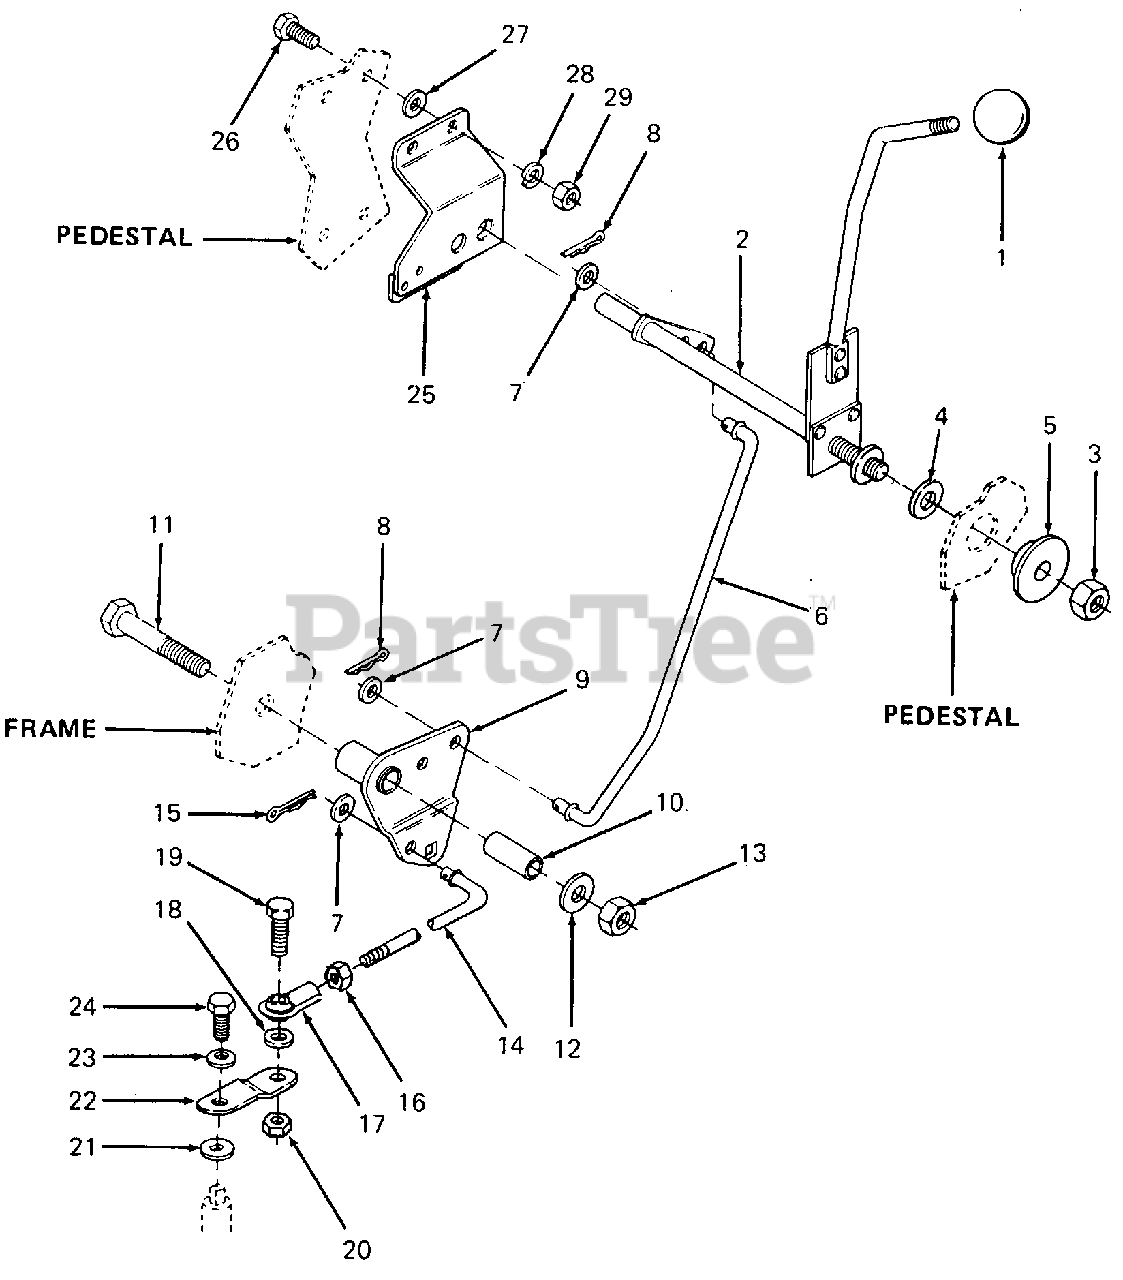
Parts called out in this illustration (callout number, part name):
1	Knob, Control
2	Shifter Assy
3	Nut, Hex Top Lock, 1/2-20
4	Washer, Friction
5	Spacer, Shoulder
6	Rod, Shift
7	Washer, Flat, .406 X .75 X.063 Thk
8	Pin, Cotter, 1/8 X 1.0 Lg
9	Cam, Shift
10	Sleeve, .380 X .623 X 1.555 Lg
11	Screw, Hex Cap, 3/8-16 X 2.25 Lg GR5
12	Washer, Flat, .385 X .87 X 0.6 Thk HDN
13	Nut, Hex Center Lock, 3/8-16
14	Rod, Shift
15	Pin, Internal Cotter
16	Nut, Hex Jam, 3/8-24
17	Ball Joint
18	Washer, Flat, .385 X .62 X .063 Thk
19	Screw, Hex Cap, 3/8-24 X 1.0 Lg
20	Nut, Hex Center Lock Jam, 3/8-24
22	Bracket, Shifter
23	Washer, Bell, .265 X .75 X .062 Thk
24	Screw, Hex Patch Lock, 1/4-28 X .62 Lg
25	Bracket, Clutch Handle
26	Screw, Hex Cap, 1/4-20 X .62 Lg GR5
27	Washer, Flat, .281 X .75 X .105 Thk
28	Washer, Lock, 1/4
29	Nut, Hex, 1/4-20 GR5
